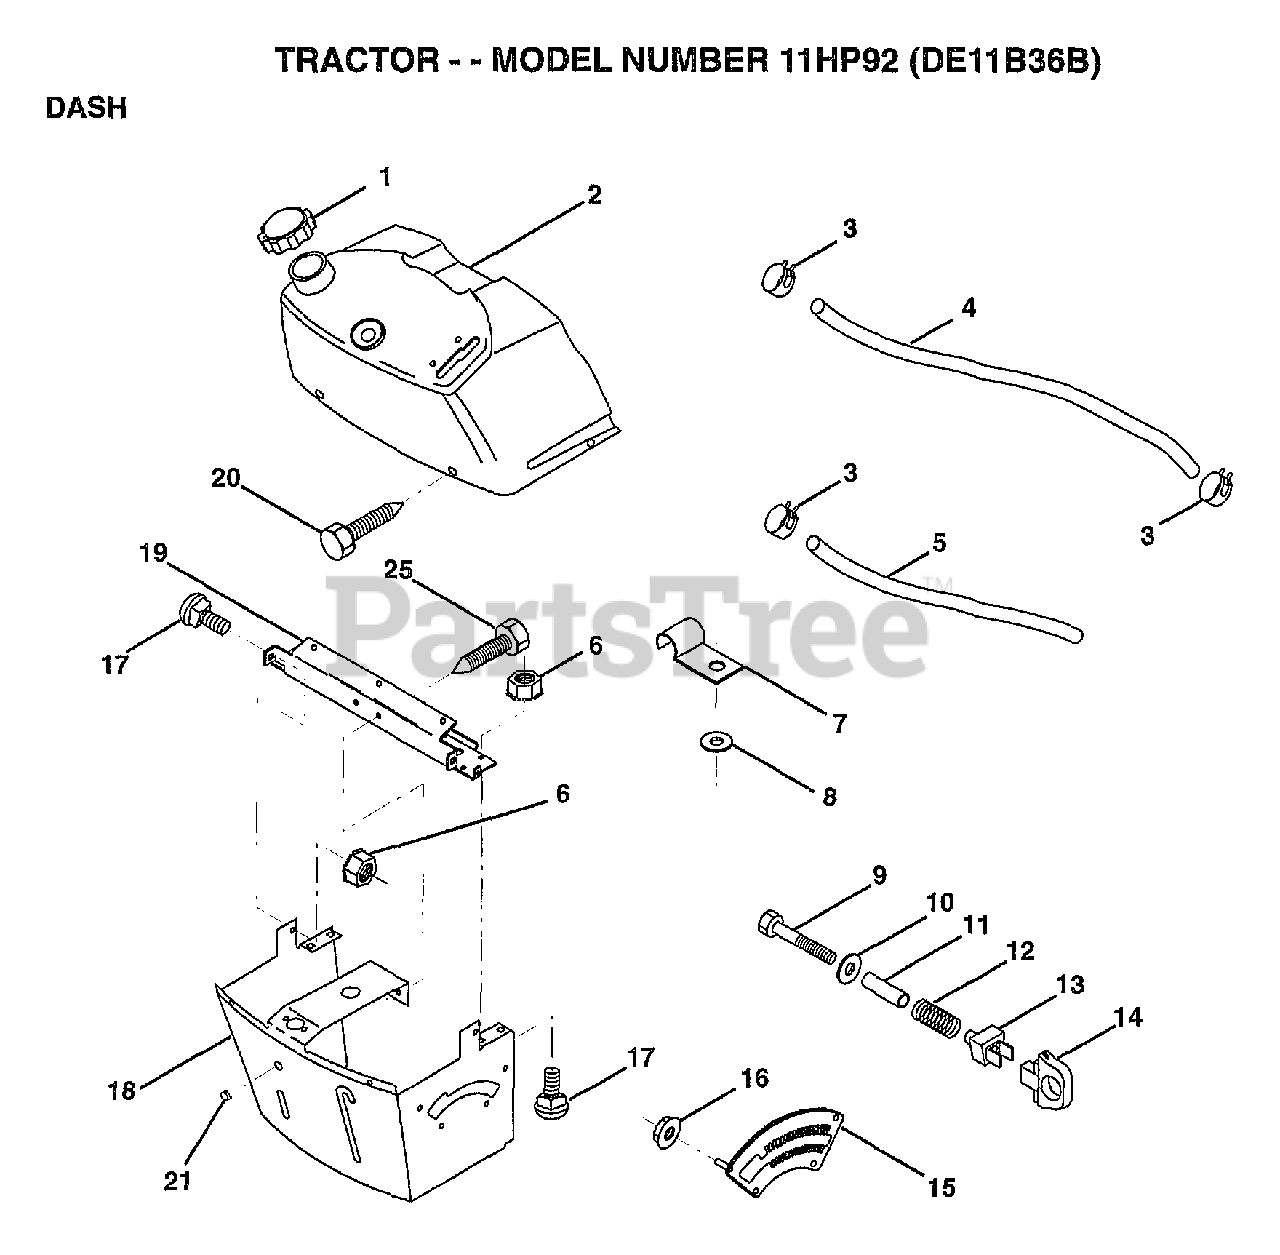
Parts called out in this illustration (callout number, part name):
1	CAP BLK FUEL LR
2	TANK.ASM.DASH.LR
3	HOSE CLAMP
5	FUEL LINE T
6	NUT HXKEP 1/4X20
7	CLIP T
8	WASHER PM
9	BOLT
11	SPACER SPLIT
12	SPRING M
13	"KNOB,HGT RETAINER"
14	KNOB
15	ADJUSTER QUAD
16	NUT
17	BOLT
18	SUPT ASSY DASH
19	CROSS BRACE
20	SCREW.1/4-20X1/2
21	PLUG DOME
25	SCREW LT
